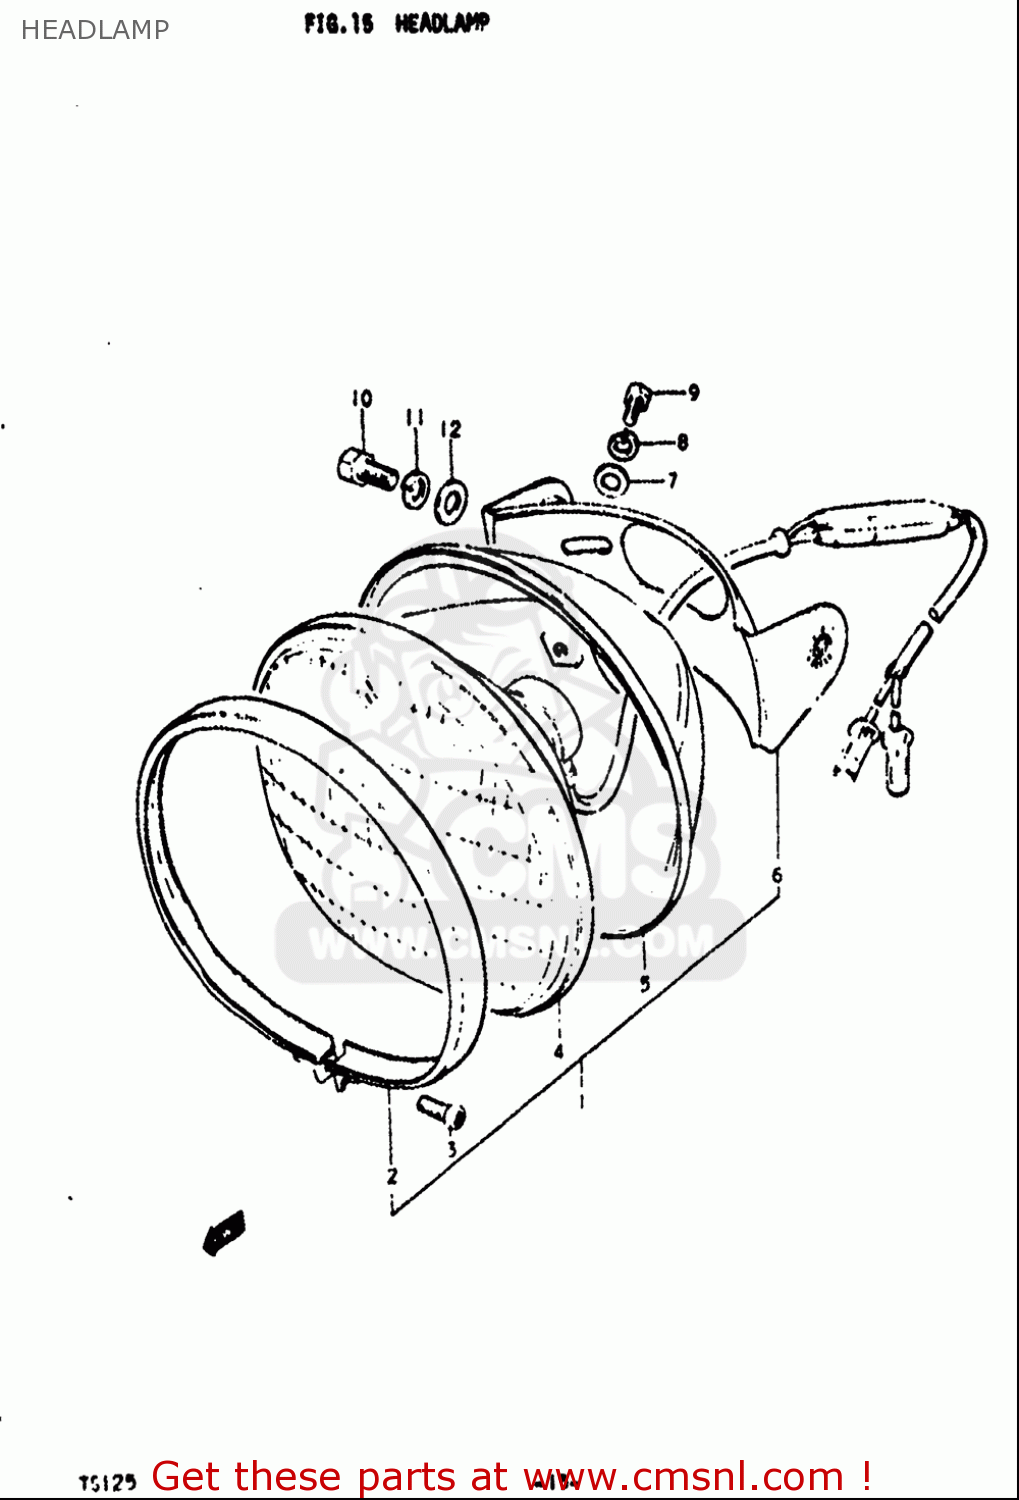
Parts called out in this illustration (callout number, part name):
3	SCREW
7	WASHER
8	WASHER,LOCK
9	BOLT
10	BOLT
11	WASHER,LOCK
12	WASHER (10.5X22X2.3)
